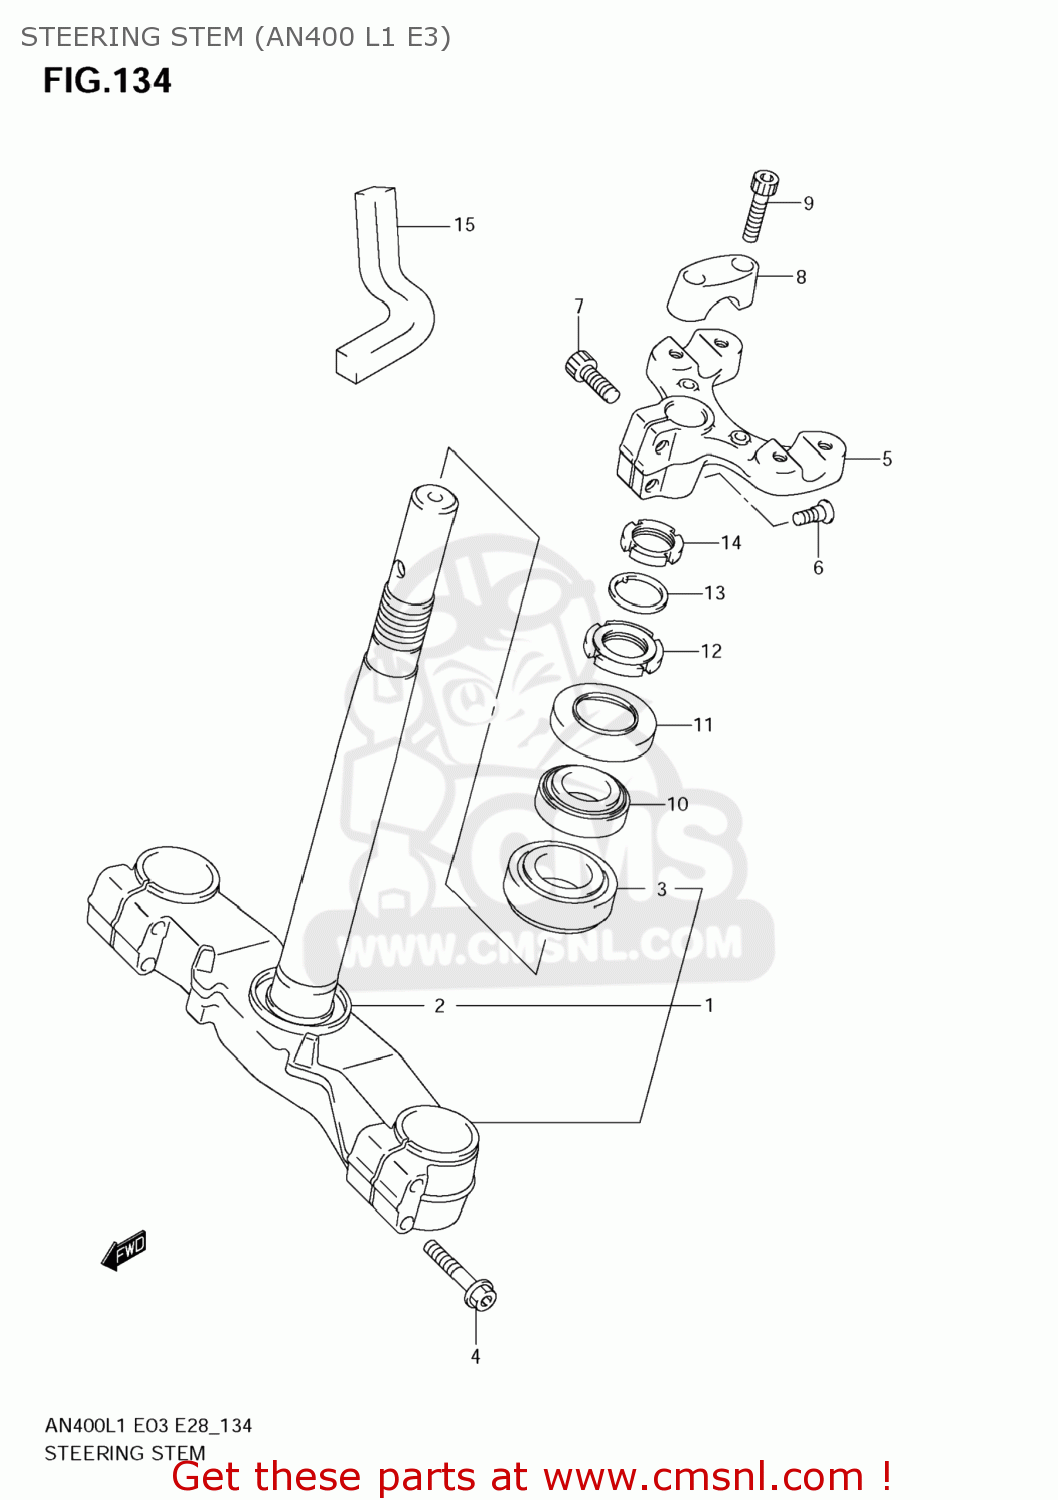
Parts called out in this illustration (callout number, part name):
1	BRACKET,FR FORK UNDER
2	SEAL,STEERING LWR
3	BEARING(30X55X17)
4	BOLT
5	BRACKET,FR FORK UPR
6	SCREW,FR FORK UPR(8X20)
7	BOLT(10X25)
8	HOLDER,HANDLE LWR
9	BOLT(8X40)
10	BEARING(25X47X15)
11	DUST SEAL,STEERING UPR
12	NUT,STEERING STEM(25X44X10)
13	WASHER
14	NUT,STEERING STEM LOCK
15	CUSHION,STEERING LOCK
